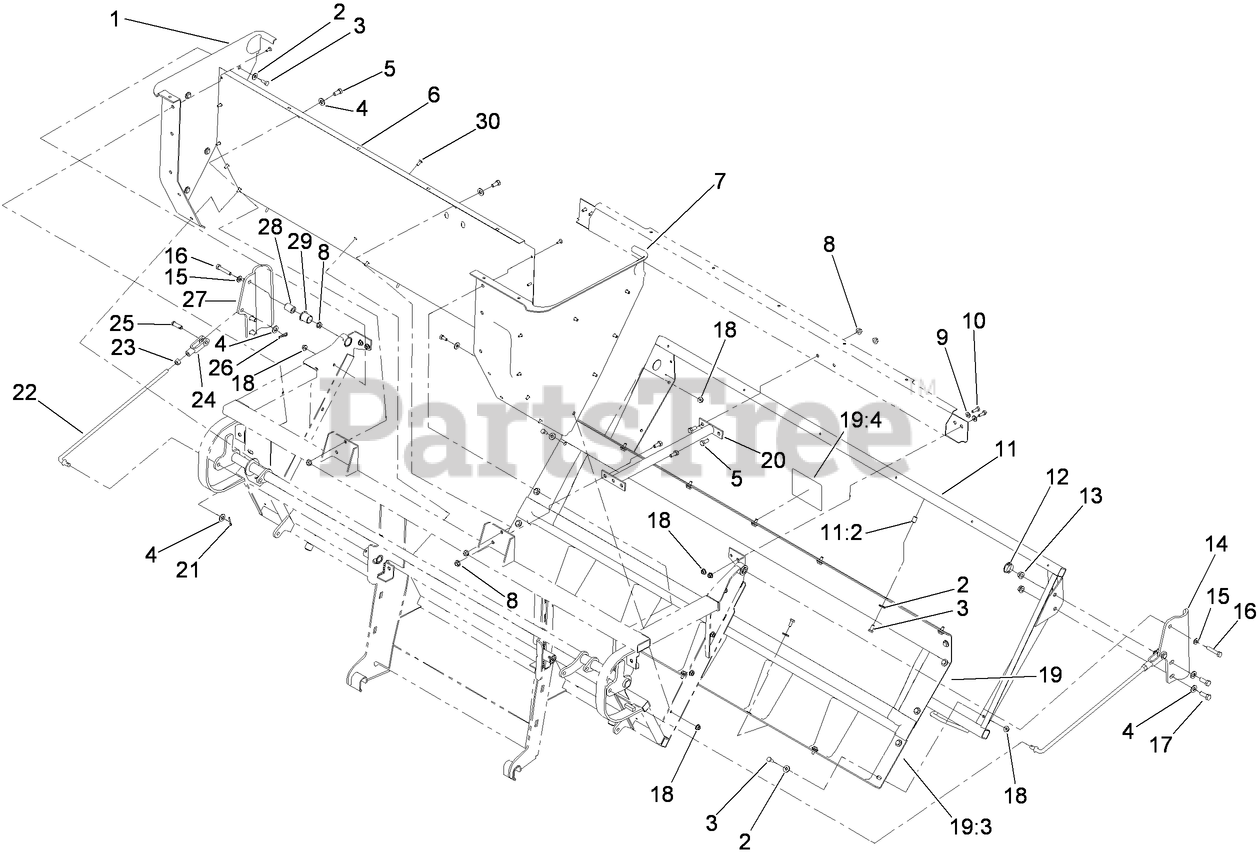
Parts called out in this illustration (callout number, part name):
1	PANEL-BAGGER, RH
2	WASHER-FLAT
3	SCREW-HH
4	WASHER-FLAT
5	SCREW-HH
6	SHEET-WALL
7	PANEL-BAGGER, LH
8	NUT-HF
9	WASHER-FLAT
10	SCREW-HH
11	DOOR ASM
11:2	INSERT-NUT
12	PLUG-DOME
13	NUT-HHF, WHIZ
14	ARM-HINGE, LH
15	WASHER-PLAIN
16	SCREW-HH
17	SCREW-HH
18	NUT-HF
19	BAG AND BOTTOM PANEL ASM
19:3	PAN-BAG, BOTTOM
19:4	DECAL-BAG WARNING
21	PIN-COTTER
22	LINK-HINGE
23	NUT-HEX
24	YOKE-LINKAGE, BRAKE
25	PIN-CLEVIS
26	PIN-COTTER
27	ARM-HINGE, RH
28	PIN-PIVOT, HINGE
29	BUSHING
30	RIVET-BLIND
